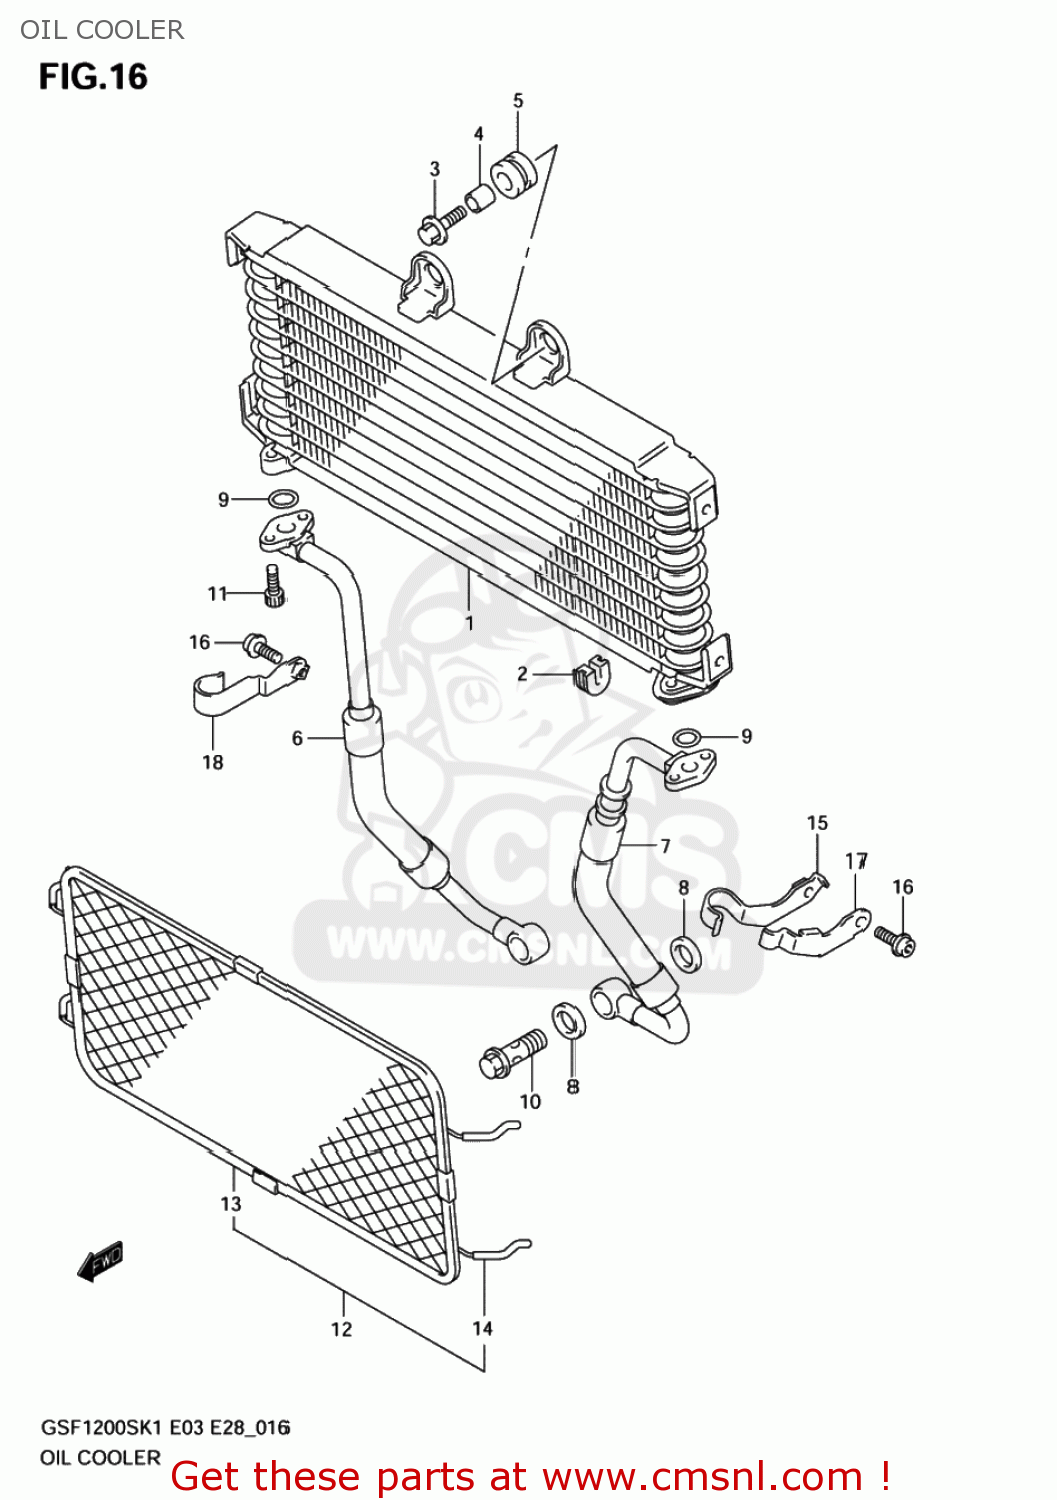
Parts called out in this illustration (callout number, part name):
1	COOLER ASSY,OI
2	CUSHION,OIL COOLER NO.2
3	BOLT(6X20)
4	SPACER(6.5X10X10)
5	CUSHION
6	HOSE COMP,OIL
7	HOSE COMP,OIL
8	GASKET(16X22X2) (NAS)
9	O RING(D:2.4,ID:11.8)
10	BOLT UNION
11	BOLT,OIL FILLE
12	GUARD,OIL COOLER
13	PROTECTOR,CTR
14	HOSE(3X5X600)
15	CLAMP,OIL HOSE,L
16	BOLT(6X16)
17	GUIDE,OIL HOSE,L
18	CLAMP,OIL HOSE,R
